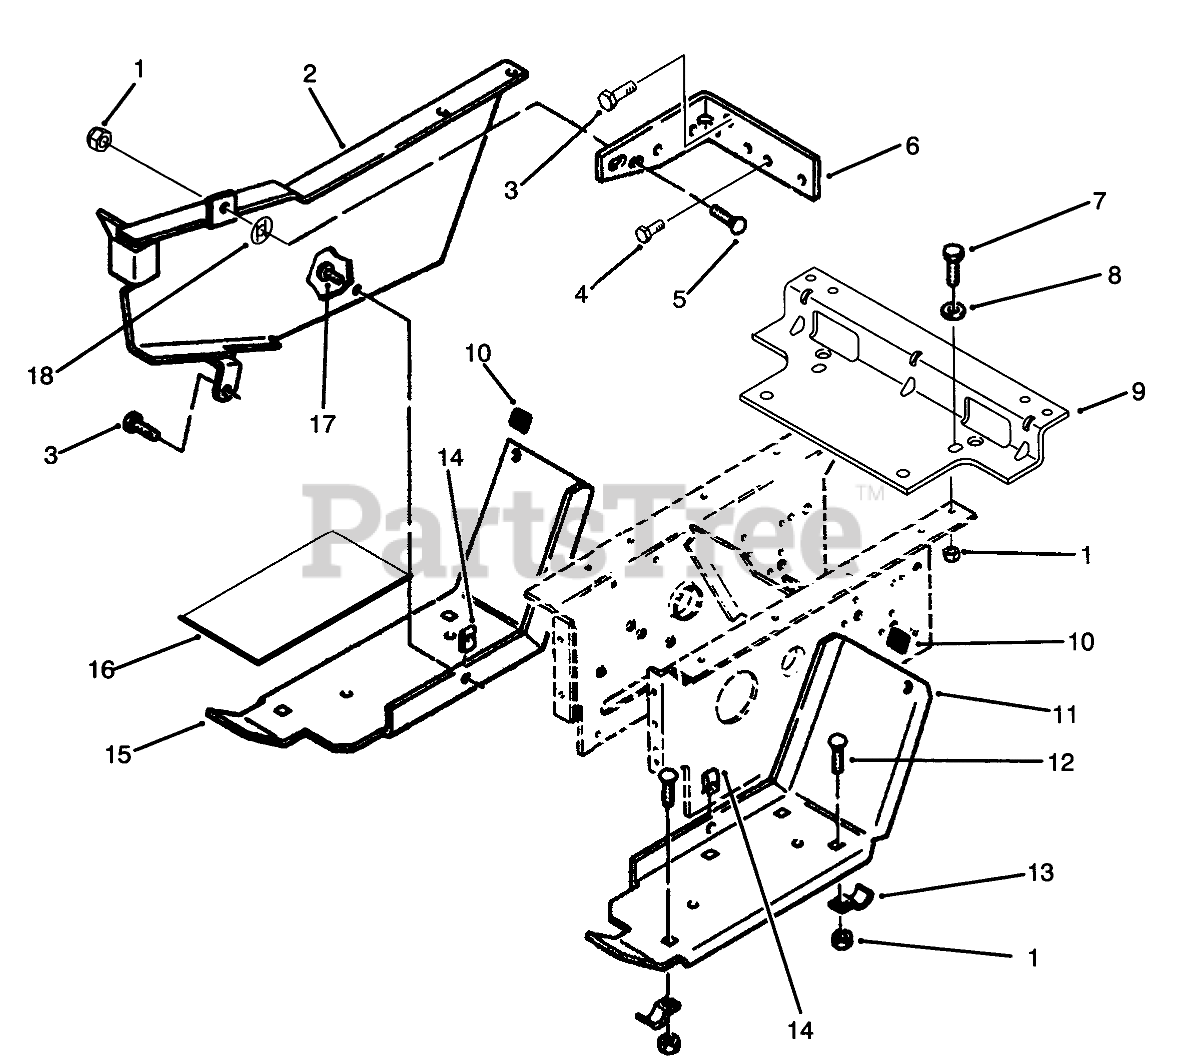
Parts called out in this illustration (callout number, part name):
1	NUT-LOCK, NI
2	GUARD - BELT WA R
3	SCREW
4	Bolt
5	BOLT-CARR
6	BRACKET-BELTB
7	SCREW-HH
8	WASHER-PLAIN
9	Bracket-Fender
10	BUMPER
11	FOOTREST LH R
12	BOLT-CARR
13	BRACKET
15	Footrest-RH
16	PAD FOOTREST
17	Screw
18	NUT-PUSH
